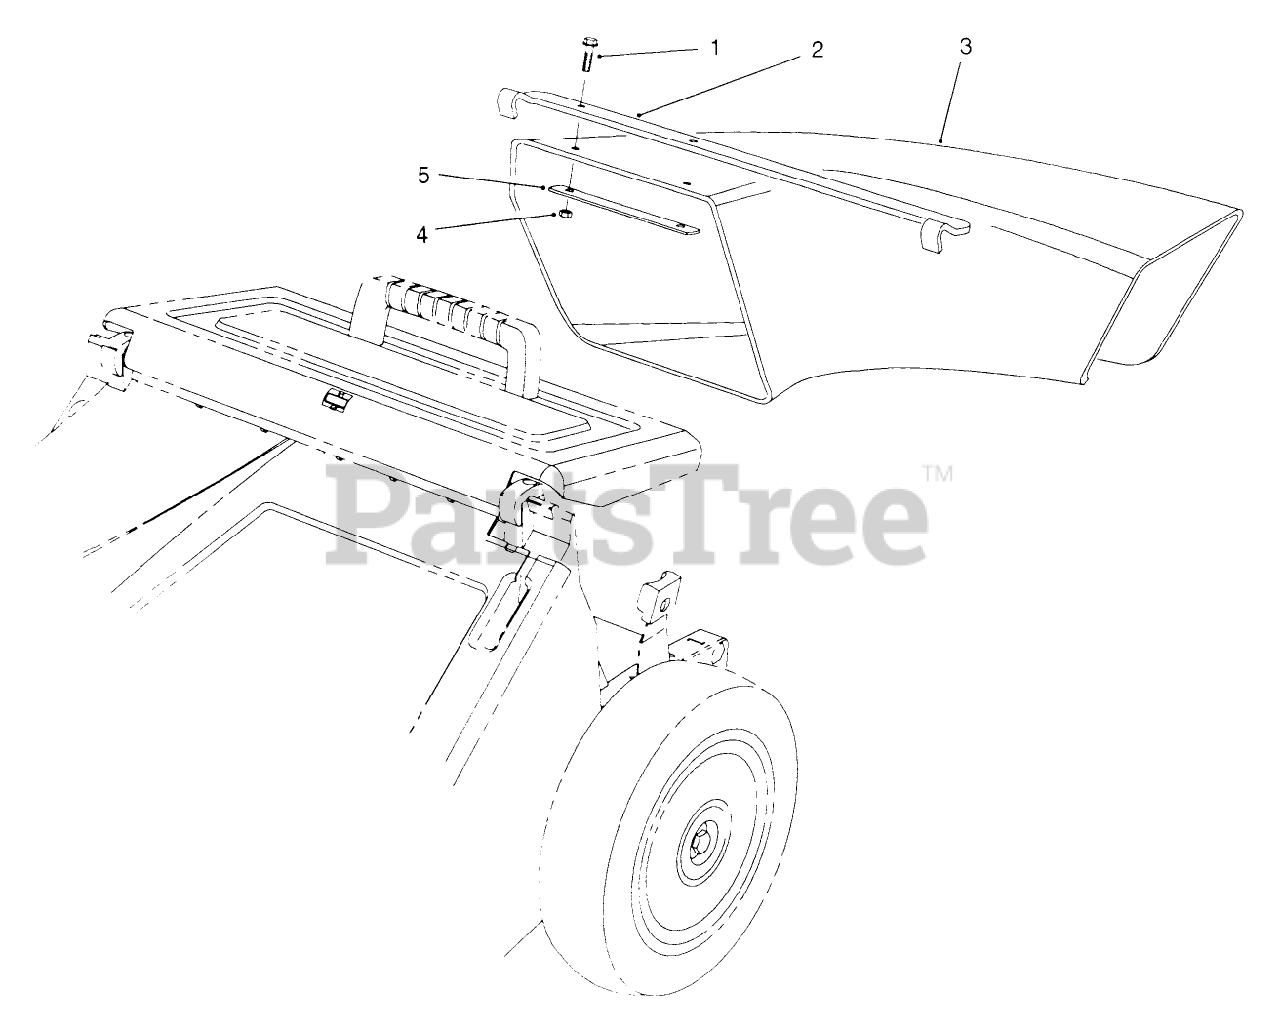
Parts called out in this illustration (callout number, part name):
1	SCREW-HWH
2	CHUTE HANGER BRACKET*
4	NUT-LOCK, NI
